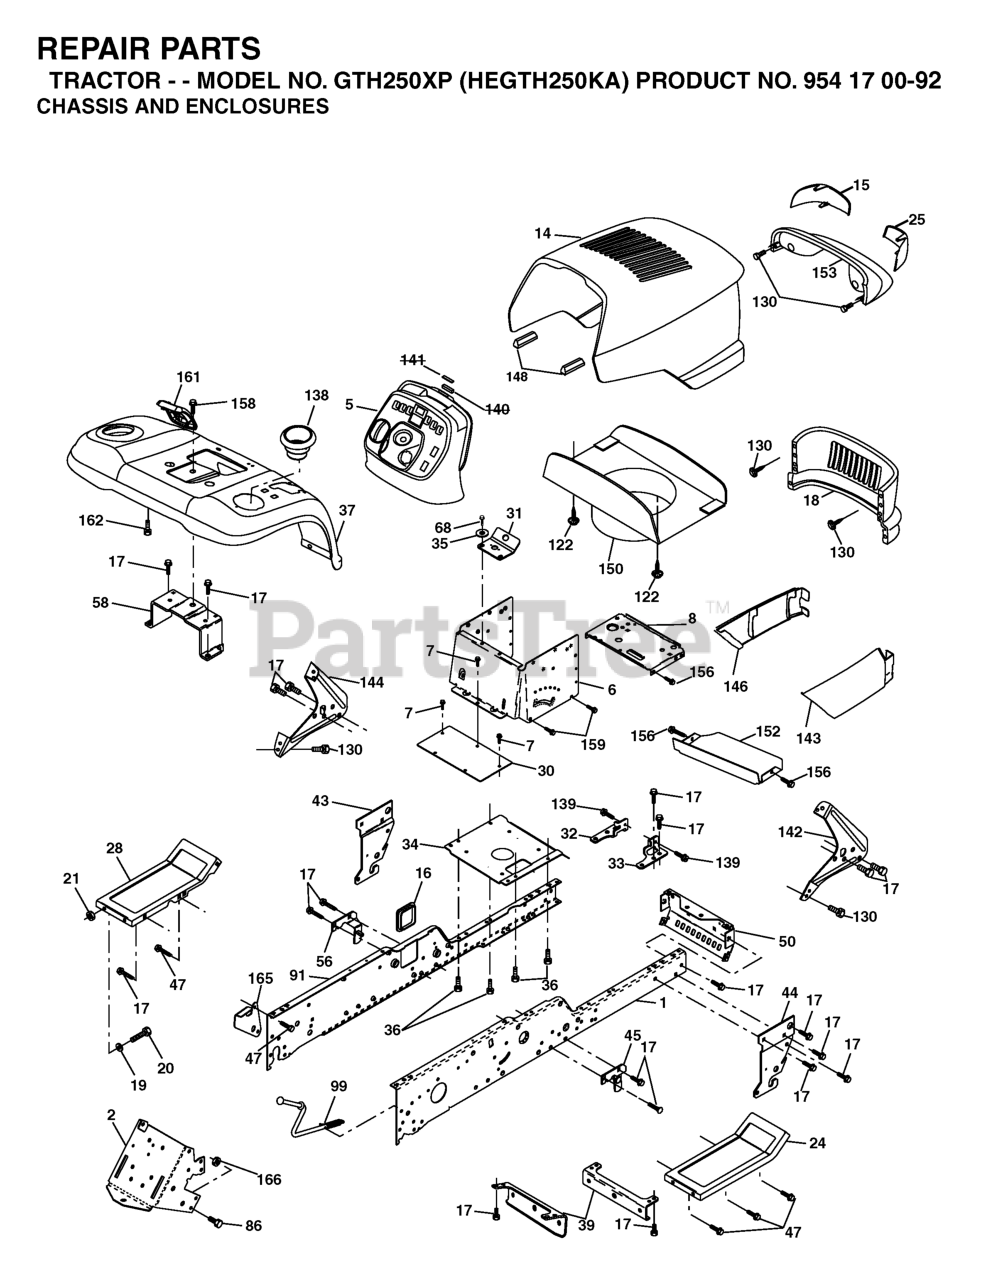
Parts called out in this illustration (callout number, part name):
1	KIT.RAIL.CHASS.RH.GT
2	DRAWBAR, GT
5	DASH.STEALTH.YTGT.2CYL.BLK
6	DASH VGT, LOWER
7	SCREW
8	SUPPORT, BATTERY
14	HOOD ASM.
15	LENS RH
16	COVER ACCESS
17	SCREW 3/8-16X3/4
18	GRILLE
19	WASHER
20	BOLT
21	NUT
24	FOOTREST PNT RH
25	LENS LH
28	FOOTREST PNT LH
30	SADDLE.HYDRO.95
31	BRACKET SUPT 1-PC VGT STEERING
34	PLATE ASM ENG CHASSIS
35	WASHER
36	SCREW 5/16"
37	FENDER, PNT
39	BRACKET AXLE, FRONT
43	FRONT SUSPENSION BRKT LH
44	FRONT SUSPENSION BRKT RH
45	BRACKET, ASM., SUSP CHASSIS RH
50	BRACKET, CHASSIS FRONT
56	BRACKET ASM., SUSP CHASSIS LH
58	BRACKET ASM., FENDER
68	Screw 5/16-18 x 1/2 Hex, Self Tapping 5/16-18 x 1/2
86	BOLT FIN HEX 7/16-14 X 1
91	KIT.RAIL.CHASS.LH.GT
99	ROD ASM, BYPASS
122	SCREW.HEX.WS.HD.8-18 X 7/8
130	SCREW
138	CUPHOLDER
139	BOLT, SHOULDER 5/16-18
142	BRACKET DASH STEALTH(R)
143	SKIRT GRILLE RH
144	BRACKET DASH STEALTH LH
146	SKIRT GRILLE LH
148	EXTRUSION BUMPER (3 2) (2 2)
150	DUCT HEAT HOOD
152	BROWNING SHIELD
153	LIGHT ASM.
156	SCREW
158	SCREW 3/8-16X1/2
159	SCREW, 3/8-16X3/4
161	CONSOL.FUEL.WINDOW.BLACK
162	SCREW.HI-LO.CONSOLE
165	BRACKET SUPPORT TANK
166	Nut, Crownlock Hex 7/16-14 unc
